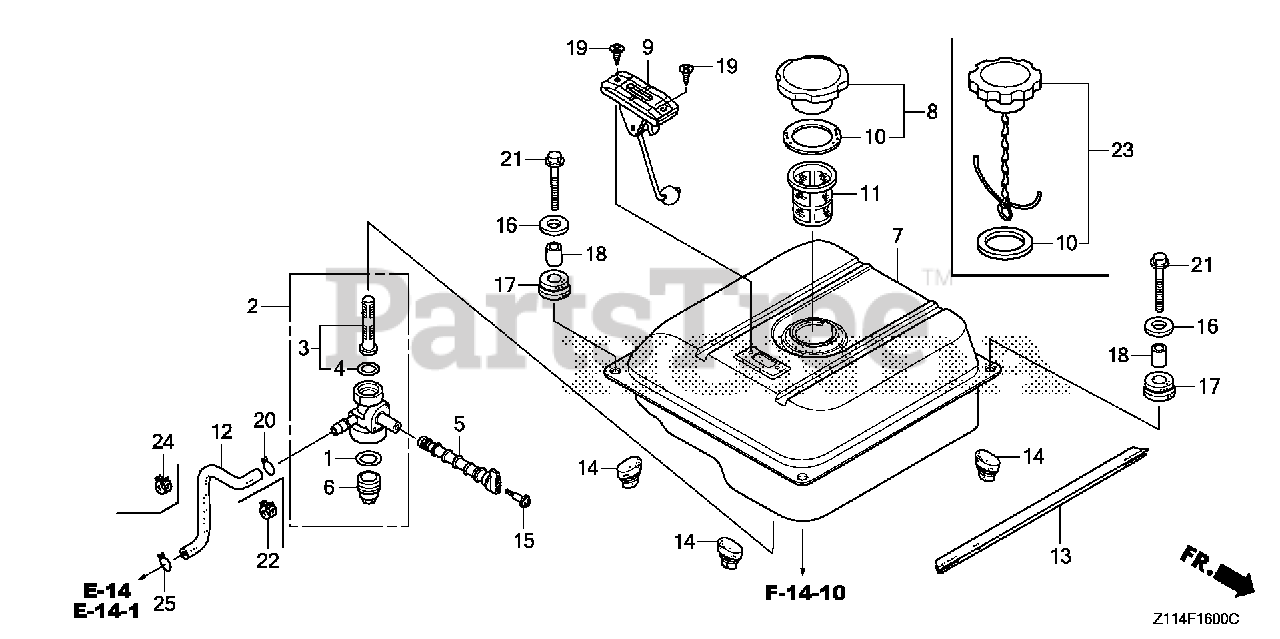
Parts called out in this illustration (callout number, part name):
1	GASKET, FUEL STRAINER CUP
2	PETCOCK ASSY.
3	SCREEN SET, FUEL STRAINER
4	O-RING (9.0X1.3)
5	LEVER, PETCOCK
6	CUP, FUEL STRAINER
7	TANK, FUEL *R280* (POWER RED)
8	CAP, FUEL FILLER
9	METER ASSY., FUEL
10	GASKET, FUEL FILLER CAP
11	FILTER, FUEL
12	TUBE, FUEL TANK (FKM) (ENGINE NO.)
12	TUBE, FUEL TANK (ENGINE NO.)
13	SEAL, FR. SEPARATOR
14	STOPPER, DISCHARGE GUARD Use up to Frame SN 1186736.
15	SCREW, PAN (4X19)
16	WASHER (6MM)
17	CUSHION, TANK RUBBER
18	COLLAR, TANK CUSHION
19	SCREW, FLAT (5X10)
20	CLIP, TUBE (B8)
21	BOLT, FLANGE (6X22)
22	CLIP, TUBE (D8)
24	CLIP, TUBE (D8)
25	CLIP, TUBE (B8)
